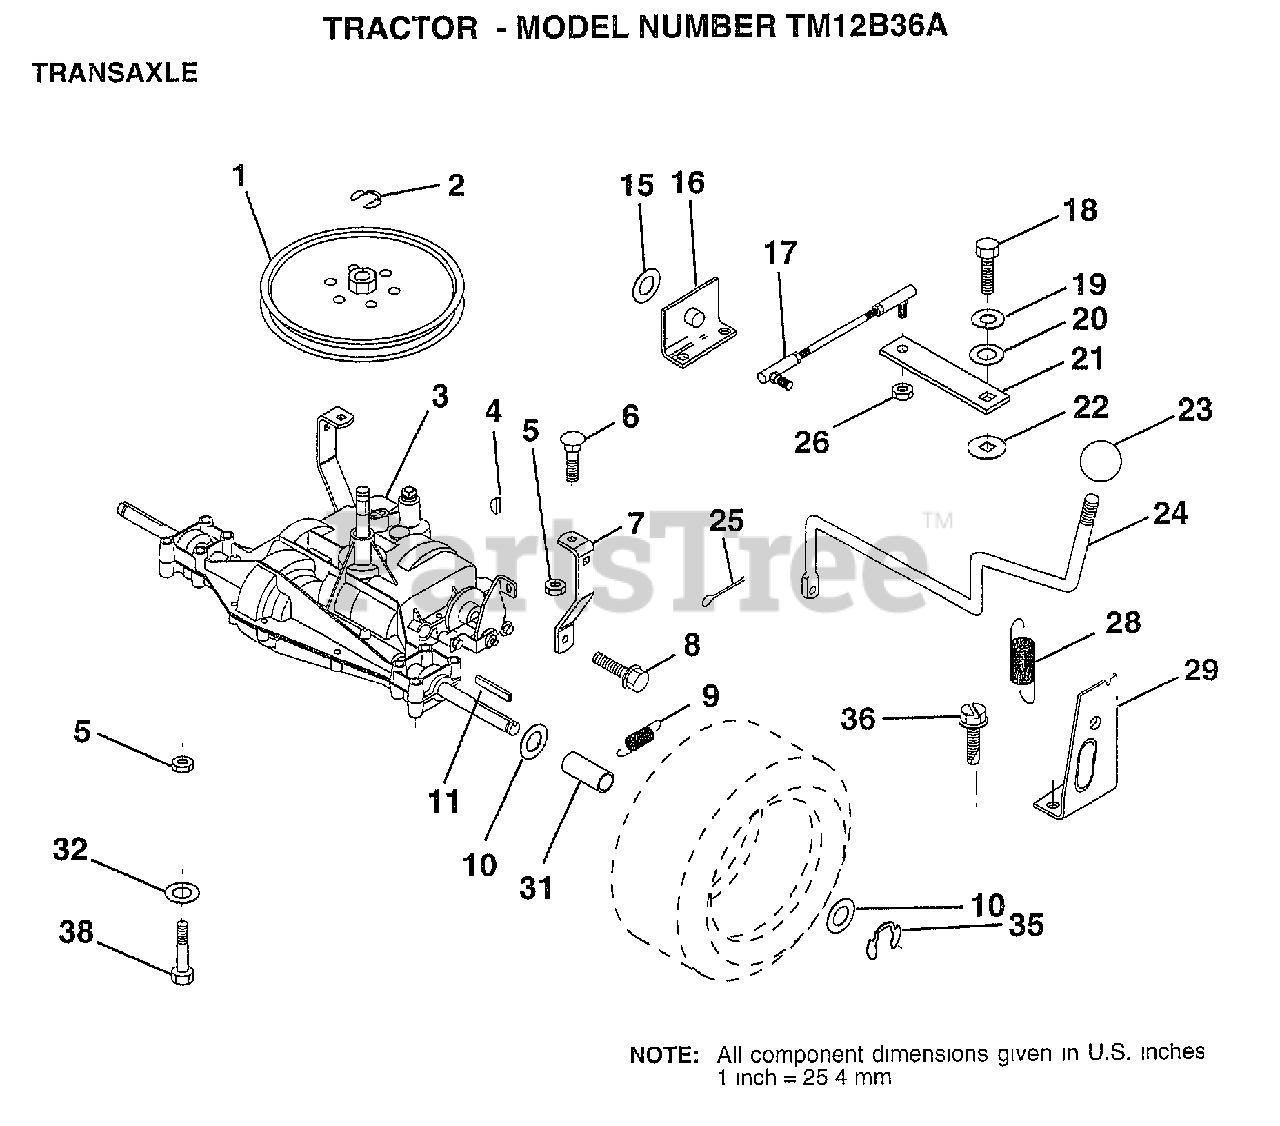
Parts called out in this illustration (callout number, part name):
1	PULLEY
6	BOLT
7	"STRAP,TORQUE"
8	SCREW
9	SPRING.BRAKE.RETU
10	WASHER
11	SQUARE KEY
16	"SUPT,HDLE SHT LH"
17	LINK SHIFT
18	BOLT.1/4-28.W/PAT
19	LOCKWASHER
20	WASHER LT
22	WASH-SHFT PLT LT
23	KNOB T (1/2-HOLE)
24	"ROD,SHIFT"
25	PIN COTTER 1/8
26	NUT.LOCK.5/16-24
28	"SPRING,EXT"
29	"SUPT,HDLE RH"
31	SPACER AXLE
32	WASHER
35	E-RING LT
36	SCREW
38	BOLT.HX.FLG.5/16
